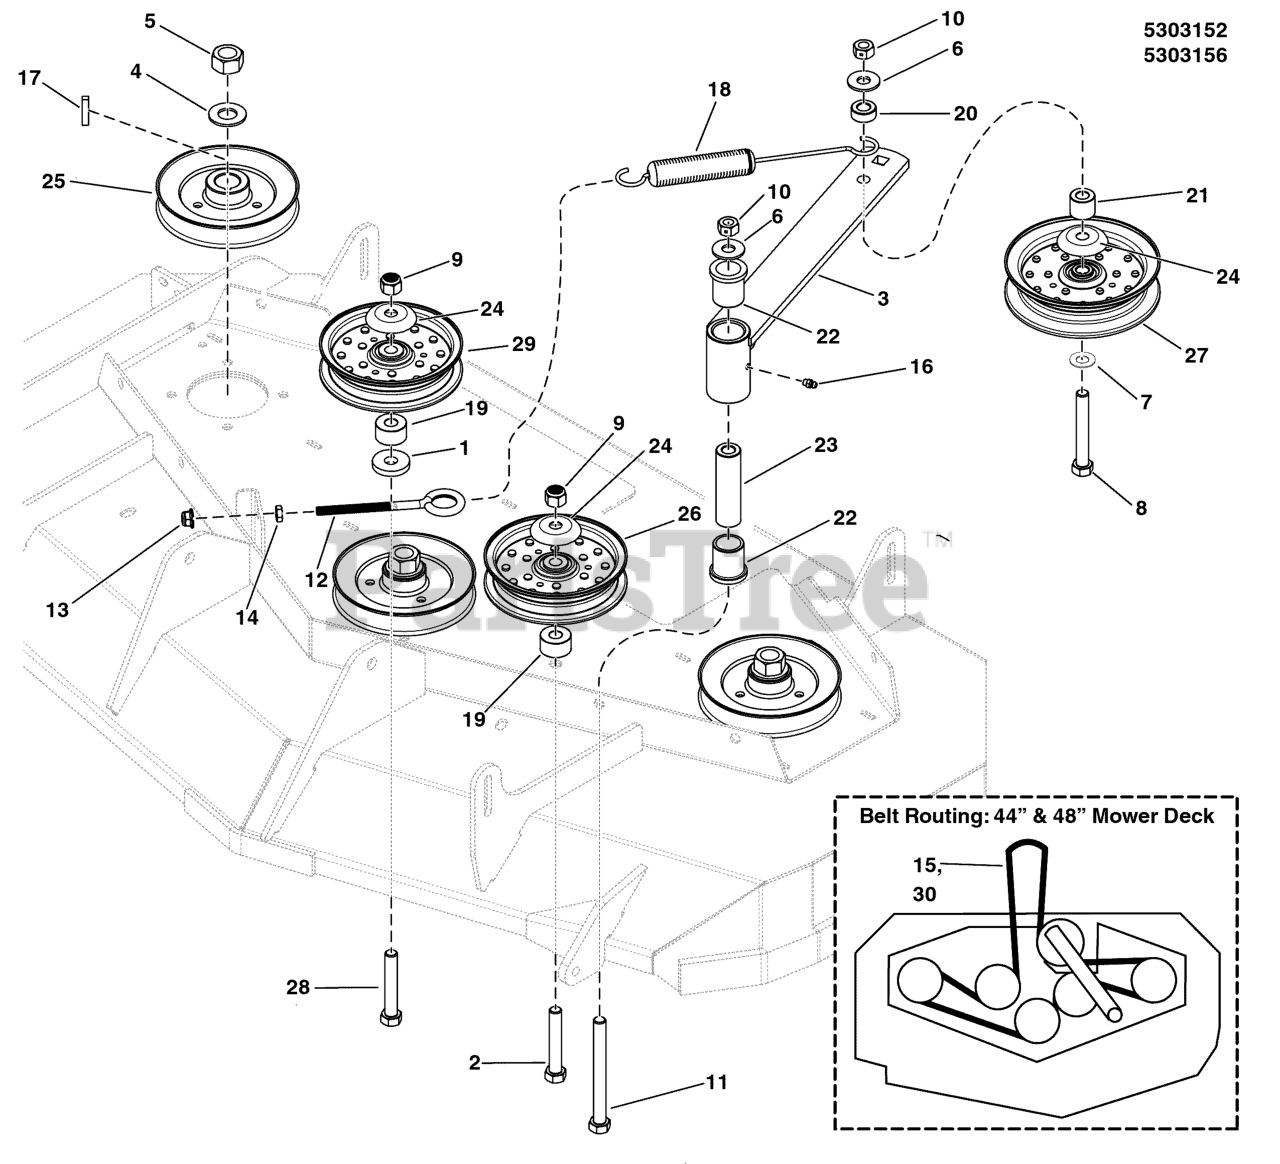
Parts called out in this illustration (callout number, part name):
1	WASHER, .53 X 1.50 X .25
2	BOLT, 1/2-13 X 2-1/2" GD5 CZ
3	WELD, IDLER ARM - BLK (12.00)
4	WASHER, 3/4 BELLEVILLE
5	NUT, 3/4-16 HEX
6	WASHER, 1/2 USS
7	WASHER, 1/2 SAE
8	BOLT, 1/2-13 X 3-1/2, HEX HD, GD5, CZ (SV)
9	NUT, 1/2-13 HEX NYLON LOCK
10	NUT, 1/2-13 HEX SIDE LOCK
11	BOLT-1/2-13 X 5 GD5 YZ
12	EYE BOLT, 3/8-16 X 6, 3.0 THREAD
13	NUT, 3/8-16 HEX NYLOCK FLANGE
14	NUT, 3/8-16 HEX JAM
15	BELT, 5V-SEC, 158.90" EL, ARAMID, WRPD, RC
16	GREASE FITTING, 1/4-28 STRAIGHT
17	KEY, 1/4 SQ X 1-1/4
18	SPRING-EXT, 1.04 ODX10.535LGX.148WR, BLK
19	SPACER, .52 X 1.25 X .70, CZ
20	SPACER, .52 X 1.00 X .44, CZ
21	SPACER, .52 X 1.00 X .88, CZ
22	BUSHING, FLANGE
23	SPACER, .52 X 1.00 X 3.50
24	SHIELD, PULLEY BEARING
25	PULLEY, 5.540OB X .985ID, SINGLE B-SEC
26	PULLEY, IDLER, 5" OD, 1"FACE, 5.75 FL
28	BOLT, 1/2-13 X 2-3/4 GD5 CZ
30	BELT, 5V, 154.50"EL, ARAMID WRPD, RC
